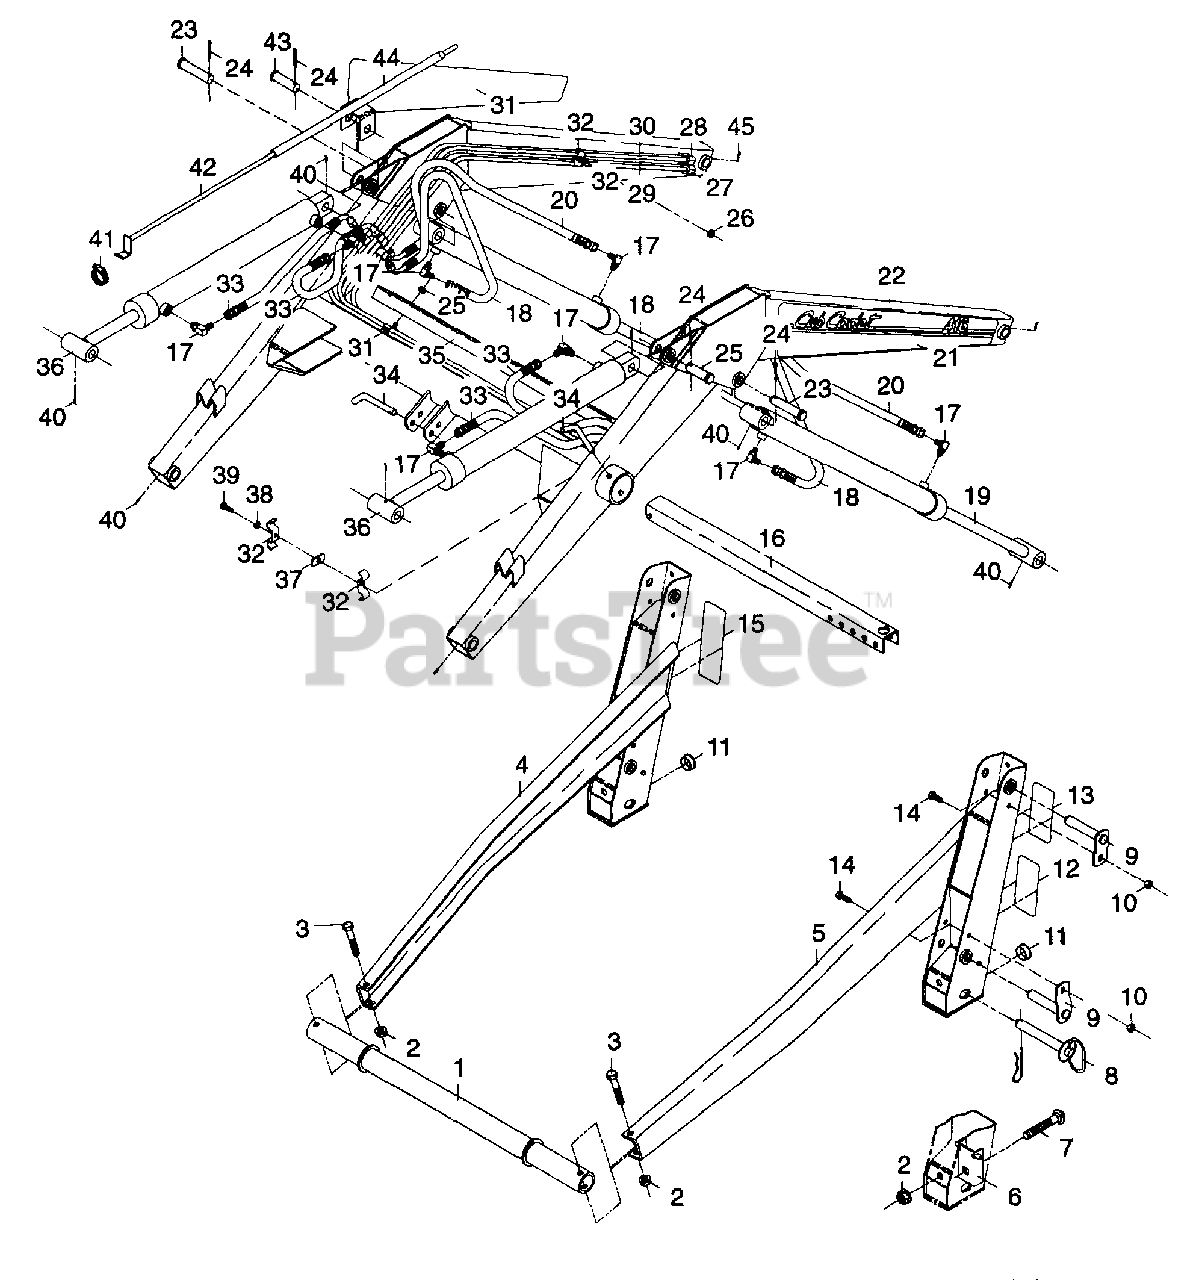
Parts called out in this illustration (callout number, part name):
1	Crossbar Weldment
2	1/2 NC Hex Flange Nut
3	1/2 x 3 Capscrew
4	Main frame assembly - RH
5	Main frame assembly - LH
6	Channel - Retainer
7	1/2 x 3-1/2 Carriage Bolt
8	Hitch Pin, 3/4 x 4
9	Pin Weldment
10	3/8 NC Locknut
12	Danger decal
13	Decal - Caution
14	3/8 NC x 1 Capscrew
15	Instruction Decal
16	Stand Weldment
17	90ø Adjustable Elbow
18	Hydraulic Hose - 24"
19	Lift Cylinder Assembly
20	Hydraulic Hose - 34"
21	Decal - 416
22	Boom frame assembly
23	Clevis Pin
24	3/16 x 1-1/2 Cotter pin
25	Clevis Pin - 3/4 x 2-1/8
26	5/16 NC Flange head locknut
27	Feedline #3
28	Feedline #1
29	Feedline #4
30	Feedline #2
31	Decal - 416
32	Feedline clamp
33	Hydraulic hose - 14"
34	Bent Pull Pin
35	Feedline cover
36	Tilt Cylinder Assembly
37	5/16 NC Tab weld nut
38	5/16 Lockwasher
39	5/16 x 3/4 Capscrew
40	1/4-28 Lube fitting
41	Hose Clamp - 5/8 - 1-1/2
42	Rod Weldment
44	Tube Weldment
45	1/4-28 x 45 Lube fitting
